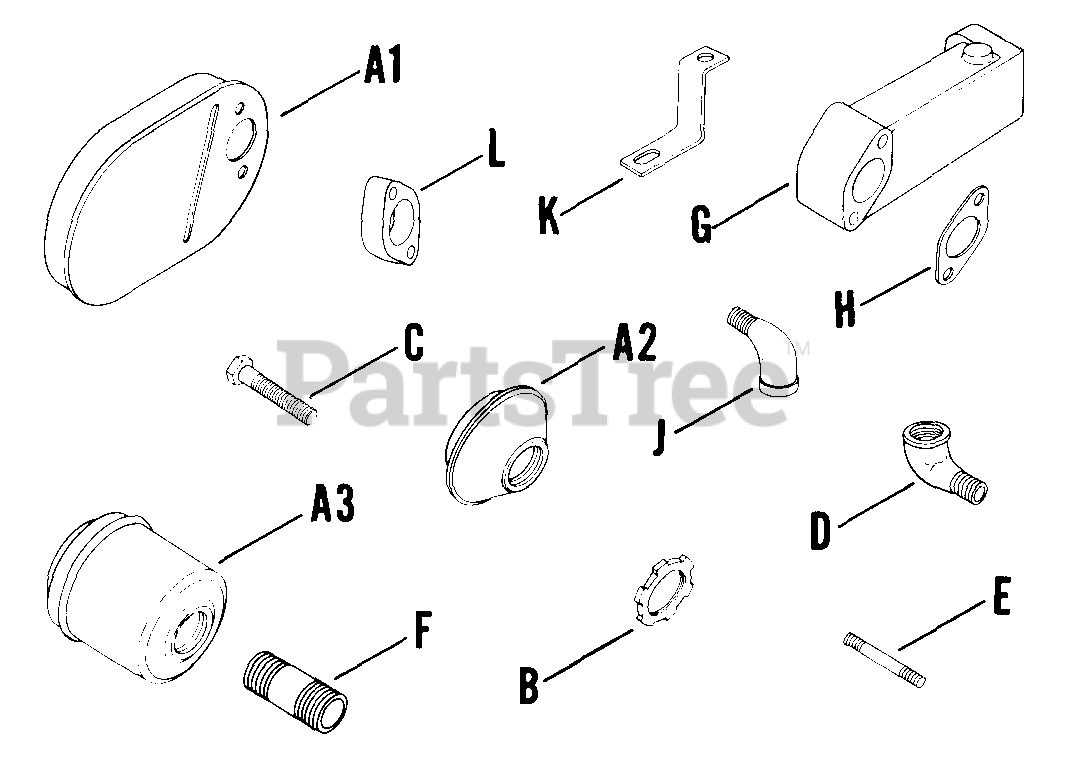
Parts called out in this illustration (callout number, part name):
A1	MUFFLER
C	SCREW - DISCONTINUED
H	GASKET - (#DSC)
